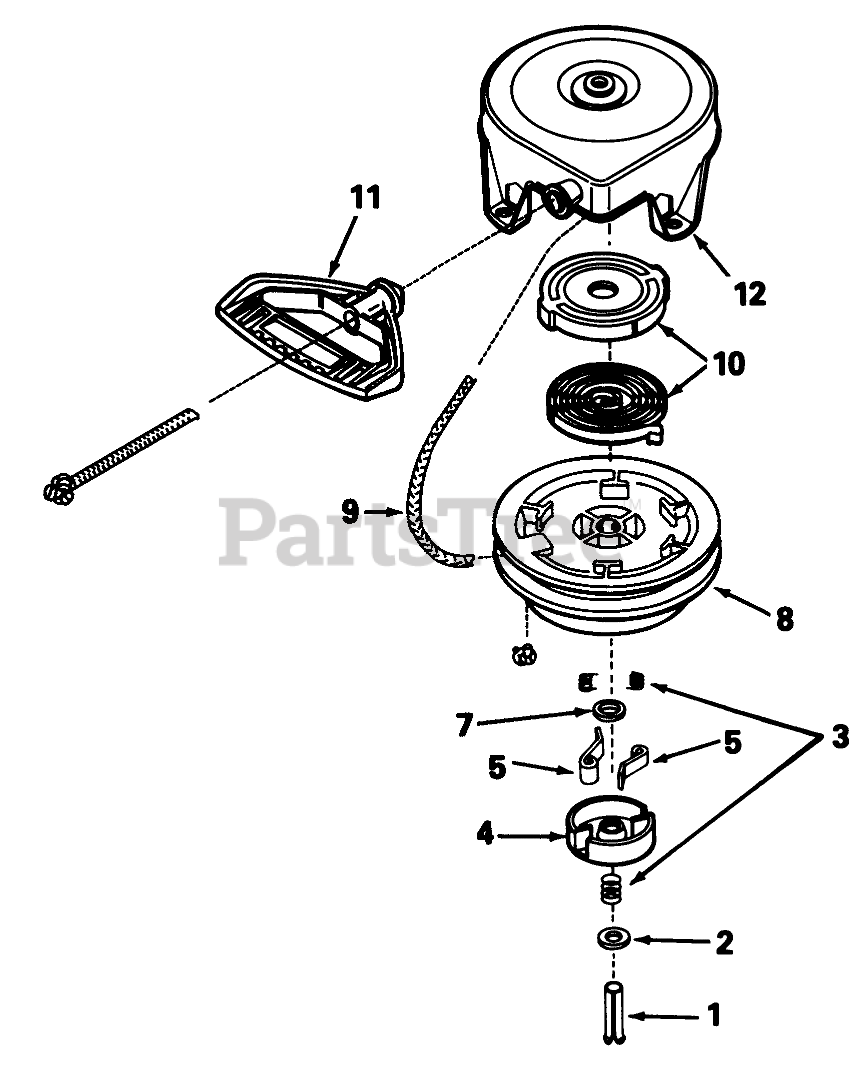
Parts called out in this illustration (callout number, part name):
1	Spring Pin ASM
3	Spring Assembly
4	Retainer
5	Dog-Starter
9	Rope, Starter
10	Spring & Keeper Assy.
11	Handle-Starter, Mitten Grip
12	Housing Assy., Starter
